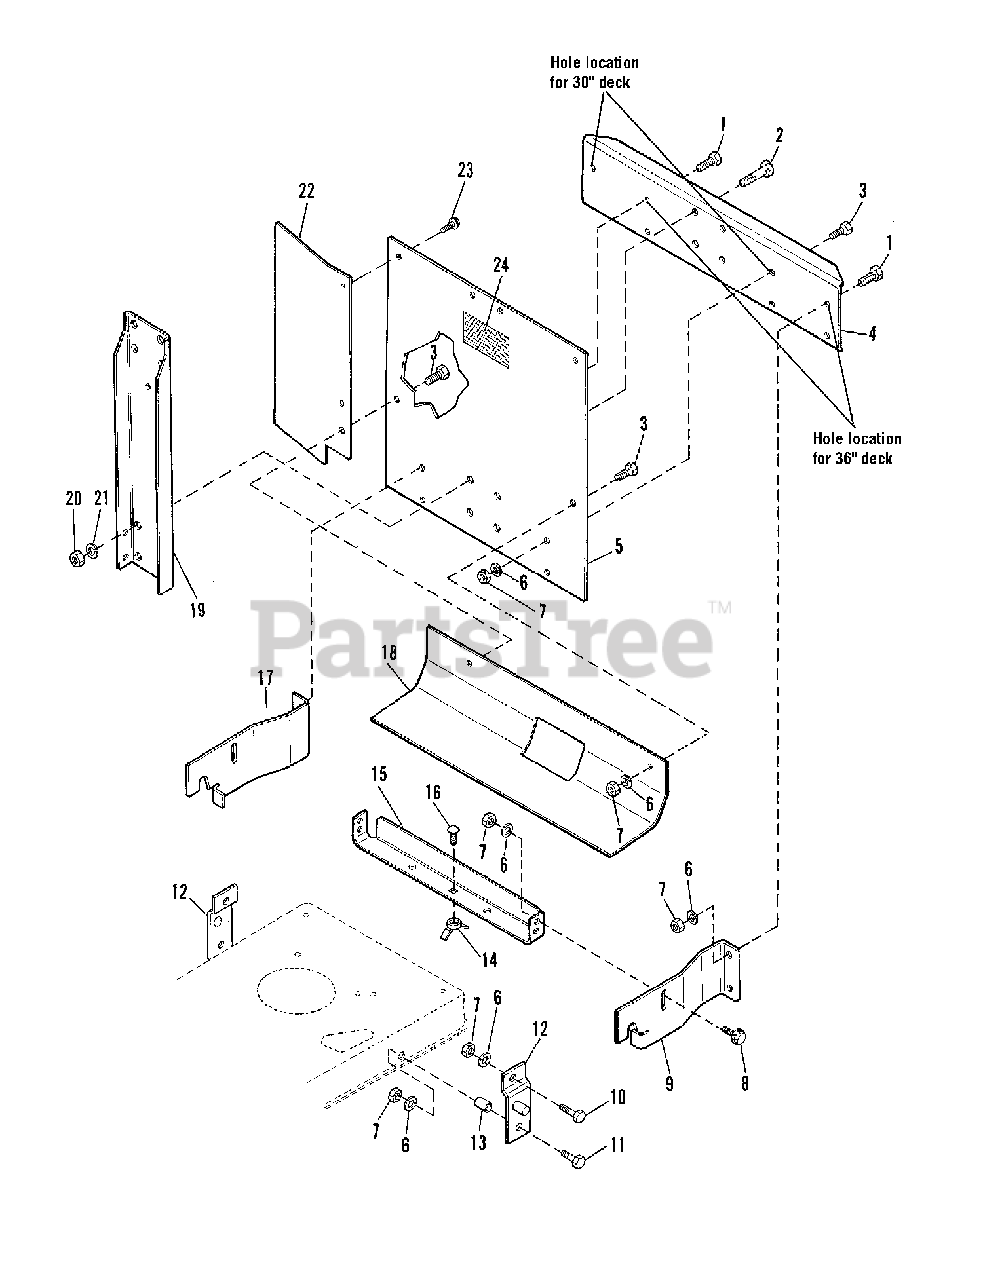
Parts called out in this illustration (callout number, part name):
1	CAPSCREW, Hex Head, 5/16-18 x 3/4
2	CAPSCREW, Hex Head, 3/8-16 x 1
3	CAPSCREW, Hex Head, 5/16-18 x 5/8
4	CHANNEL, Cross
5	HEAT DEFLECTOR, Upper
6	LOCKWASHER, 5/16
7	NUT, Hex, 5/16
8	CAPSCREW, Hex, Whiziock, 5/16-18 x 1/4
9	SUPPORT ASSEMBLY, L.H.
10	CAPSCREW, Hex Head, 5/16-18 x 1
11	CAPSCREW, Hex Head, 5/16-18 x 1-1/2
12	SUPPORT ASSEMBLY
14	WING NUT, Lock, 5/16-18
15	BRACE, Lower
16	CARRIAGE BOLT, 5/16-18 x 1
17	SUPPORT ASSEMBLY, R.H.
18	HEAT DEFLECTOR, Lower
19	SUPPORT, Upright
20	NUT, Hex Head, 3/8-16
21	LOCKWASHER, 3/8
22	HEAT DEFLECTOR, Side
23	CAPSCREW, Taptite, 5/16 x 3/8
24	DECAL, Hot Surface
